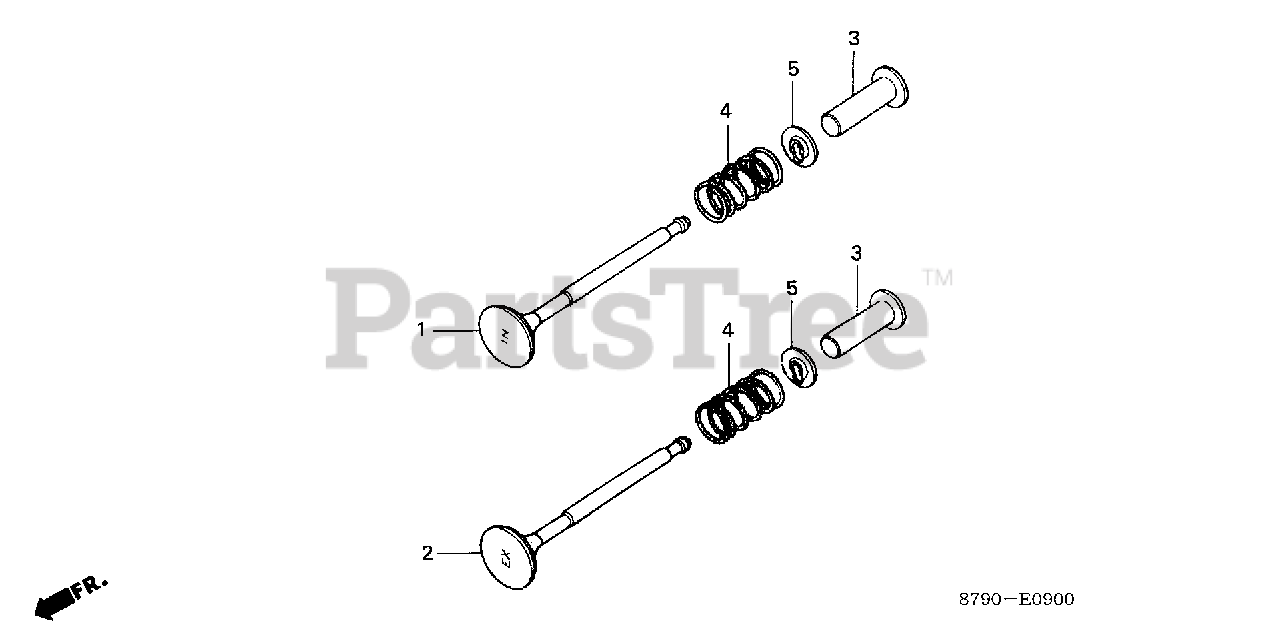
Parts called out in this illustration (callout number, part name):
1	VALVE, IN. (NOT AVAILABLE)
2	VALVE, EX.
3	LIFTER, VALVE
4	SPRING, VALVE (NOT AVAILABLE)
5	RETAINER, VALVE SPRING
